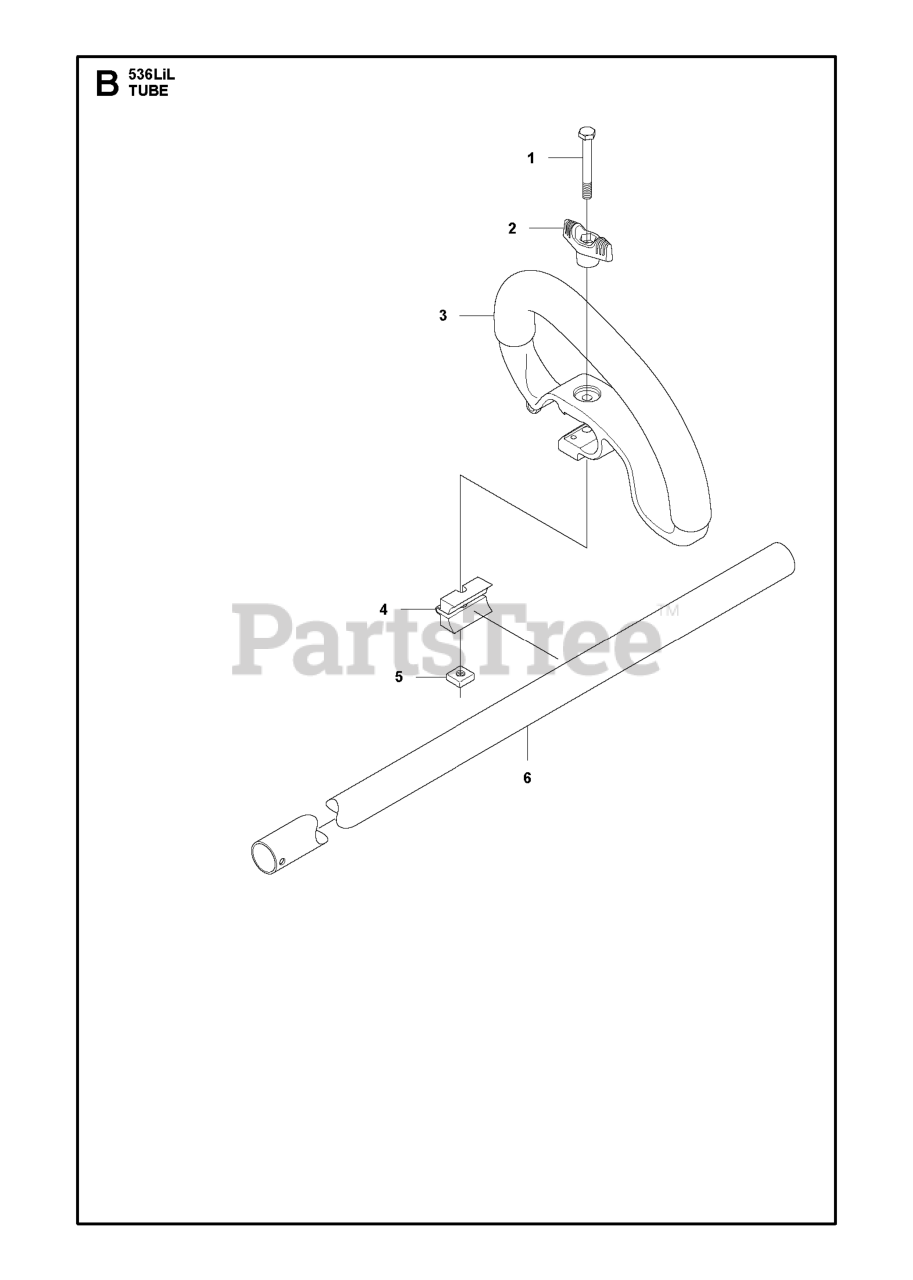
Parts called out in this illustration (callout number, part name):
1	SCREW M6X50
4	SPACER PLASTIC
6	TUBE
